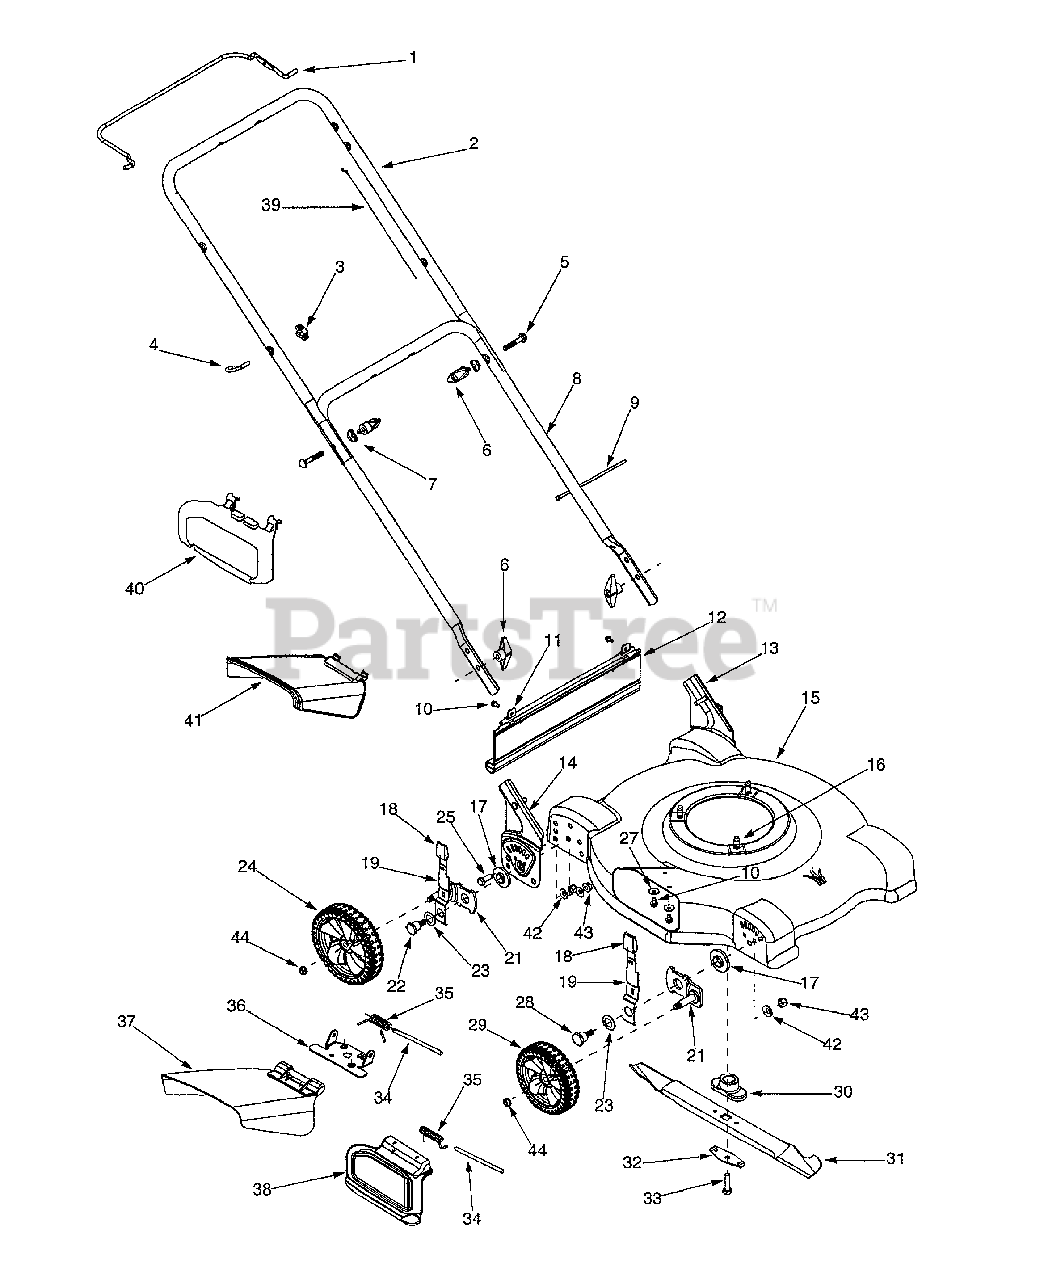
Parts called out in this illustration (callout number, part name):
3	Wing Nut
4	Eye Bolt
5	Carriage Bolt 5/16-18 x 2.0
6	Wing Nut
7	Shoulder Washer .320 ID x .93 OD
9	Cable Tie
10	TT Screw 1/4-20 x 0.5"
11	Hinge Clip
12	Trail Shield
16	Hex Washer Screw 3/8-16 x 1.0
17	Height Adjuster Bearing
18	Height Adjuster Knob
19	Spring Lever
20	Hex Cap Screw 3/8-16 x .75
21	Pivot Arm
22	Shoulder Screw
23	Bell Washer .760 ID x 1.25 OD
24	Rear Wheel 8 x 1.8
25	Hex Cap Screw 3/8-16 x 1.0
26	Flange Lock Nut 3/8-16
27	Bell Washer .265 ID x .75 OD
28	Shoulder Screw
29	Front Wheel 7 x 1.8
30	Blade Adapter
31	Blade 22"
32	Blade Bell Support
33	Hex Cap Screw 3/8-24 x 1.5
34	Hinge Pin
35	Torsion Spring
36	Chute Hinge
37	Side Discharge Chute Assembly
38	Mulching Baffle
39	Blade Control Cable - B&S
40	Snap Mulching Plug
41	Snap Discharge Chute
42	Washer Spacer.401 ID x .870 OD
43	Hex Lock Nut 3/8-16
44	Lock Nut 3/8-16
